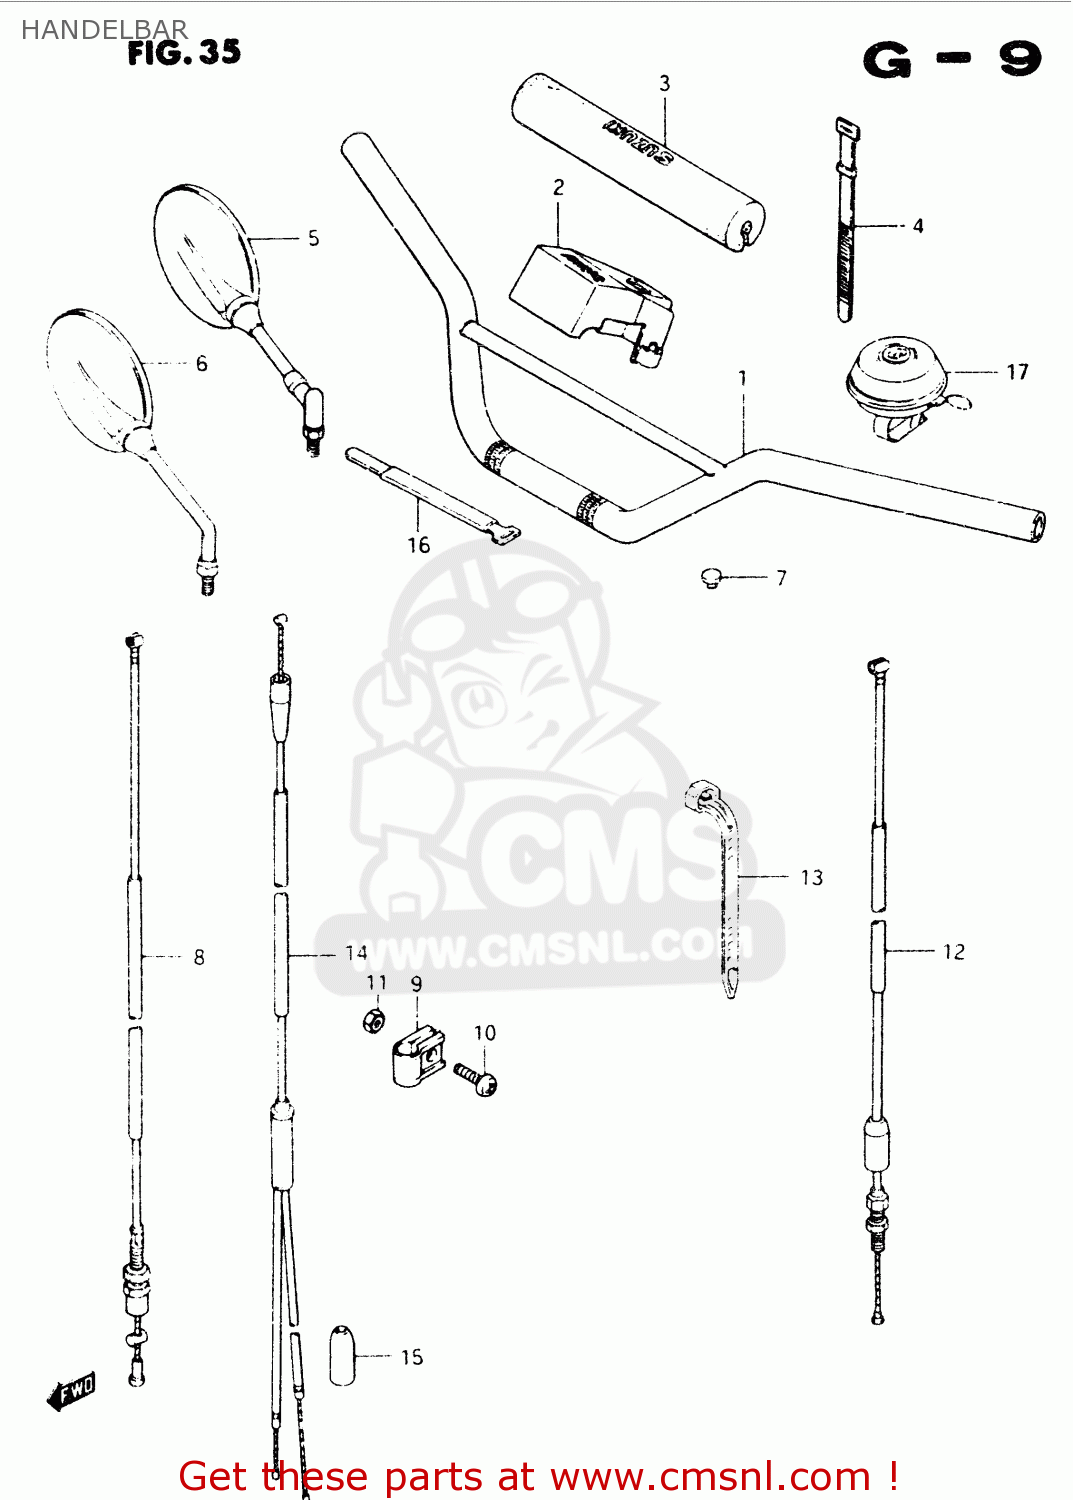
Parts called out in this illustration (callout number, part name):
1	HANDLEBAR
2	COVER,STEERING HEAD
3	PAD,CROSSBAR
4	CLAMP(L:187)
5	MIRROR ASSY,RR VIEW,R
6	MIRROR ASSY, REAR VIEW
7	CAP
8	CABLE,FR BRAKE
9	CLAMP,FR BRAKE CABLE
10	SCREW
11	NUT
12	CABLE ASSY,CLUTCH
13	CLAMP(L:165)
14	CABLE ASSY, THROTTLE
15	SEAL,DUST(7X18X30)
16	CLAMP
17	BELL ASSY
